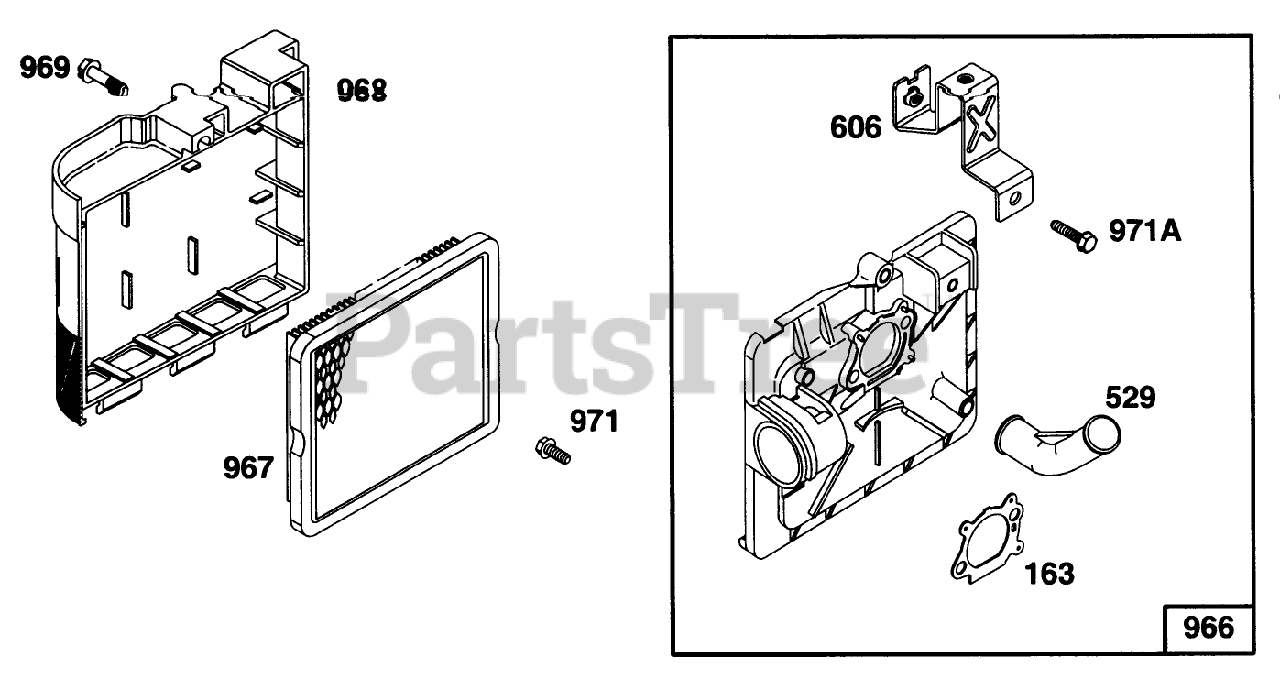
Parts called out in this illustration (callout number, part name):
163	Gasket-Cleaner, Air
529	Grommet
606	Strap-Bracket
966	Base-Primer, Air Cleaner
967	Filter-Air Cleaner, Cartridge
968	Air Cleaner Cover
969	Screw-Cover Mt.
971	Screw-Air Cleaner
971A	Screw-Hex.
